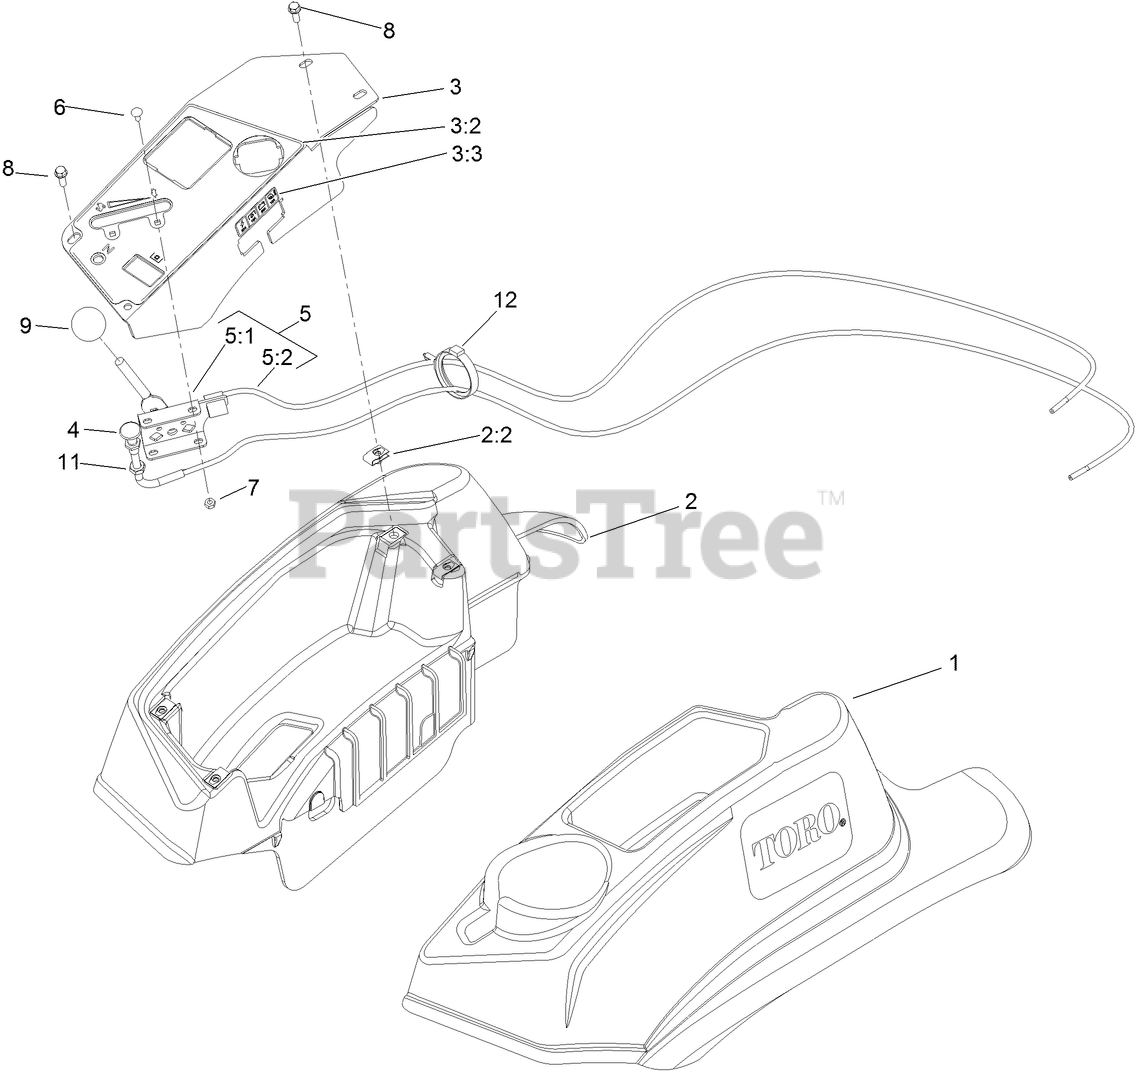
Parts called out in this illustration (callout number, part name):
1	CONSOLE-LH
2	RH CONSOLE ASM
3	CONTROL PANEL ASM
3:2	DECAL-CONTROL PANEL
3:3	DECAL-FUSES
4	CONTROL-CHOKE
5	THROTTLE CONTROL ASM
5:1	LEVER-THROTTLE
5:2	CABLE-THROTTLE
6	BOLT-CARR
7	NUT-LOCK, NI
8	SCREW-HWH
9	KNOB-BALL
11	NUT-HJ
12	CLAMP-HARNESS
